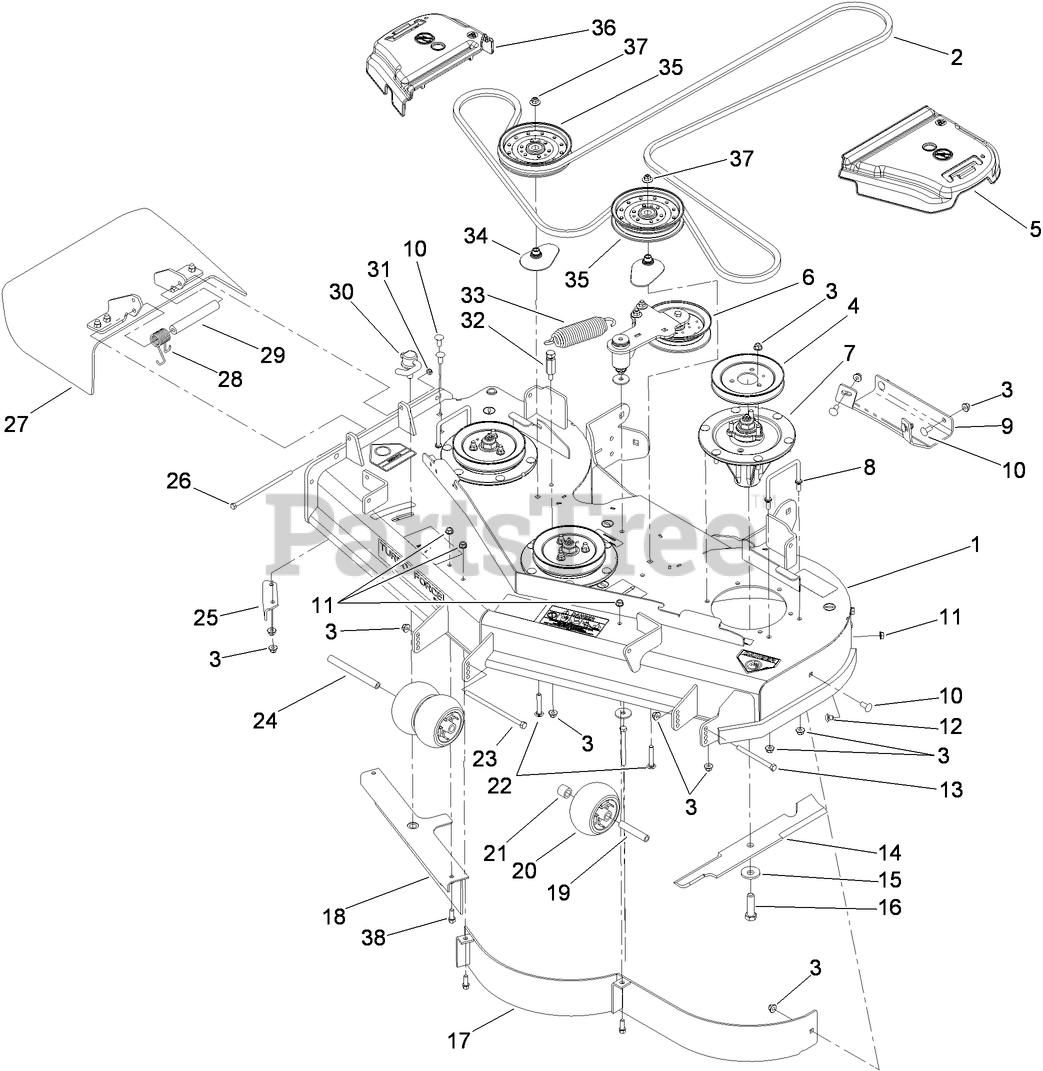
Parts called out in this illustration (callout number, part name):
1	DECK DECAL ASM
2	BELT-V
3	NUT-HF, NI
4	PULLEY
5	COVER-BELT, LH
6	IDLER ARM ASM
7	SPINDLE ASM
8	WIREFORM-COVER
9	PLATE-SKID
10	SCREW-CARR
11	NUT-HHF, WHIZ
12	SCREW-CARR
13	SCREW-HH
14	BLADE-18IN, HI FLOW
15	Washer-Blade Bolt, Heavy
16	SCREW-BLADE
17	BAFFLE ASM
18	BAFFLE
19	TUBE-SPANNER
20	ROLLER-SCALP, ANTI
21	TUBE-SPACER
22	BOLT-CARR, SHORT NECK
23	SCREW-HH
24	SPACER-WHEEL
25	BAFFLE-DISCHARGE
26	SCREW-HH
27	RUBBER DEFLECTOR ASM
28	SPRING-TORSION
29	SPACER
30	LEVER ASM
31	NUT-LOCK, NI
32	ANCHOR-SPRING, TALL
33	EXTENSION-SPRING
34	SPACER-PULLEY
35	PULLEY-IDLER, FLAT
36	COVER-BELT, RH
37	NUT-FLANGE, NI
38	SCREW-HWH
